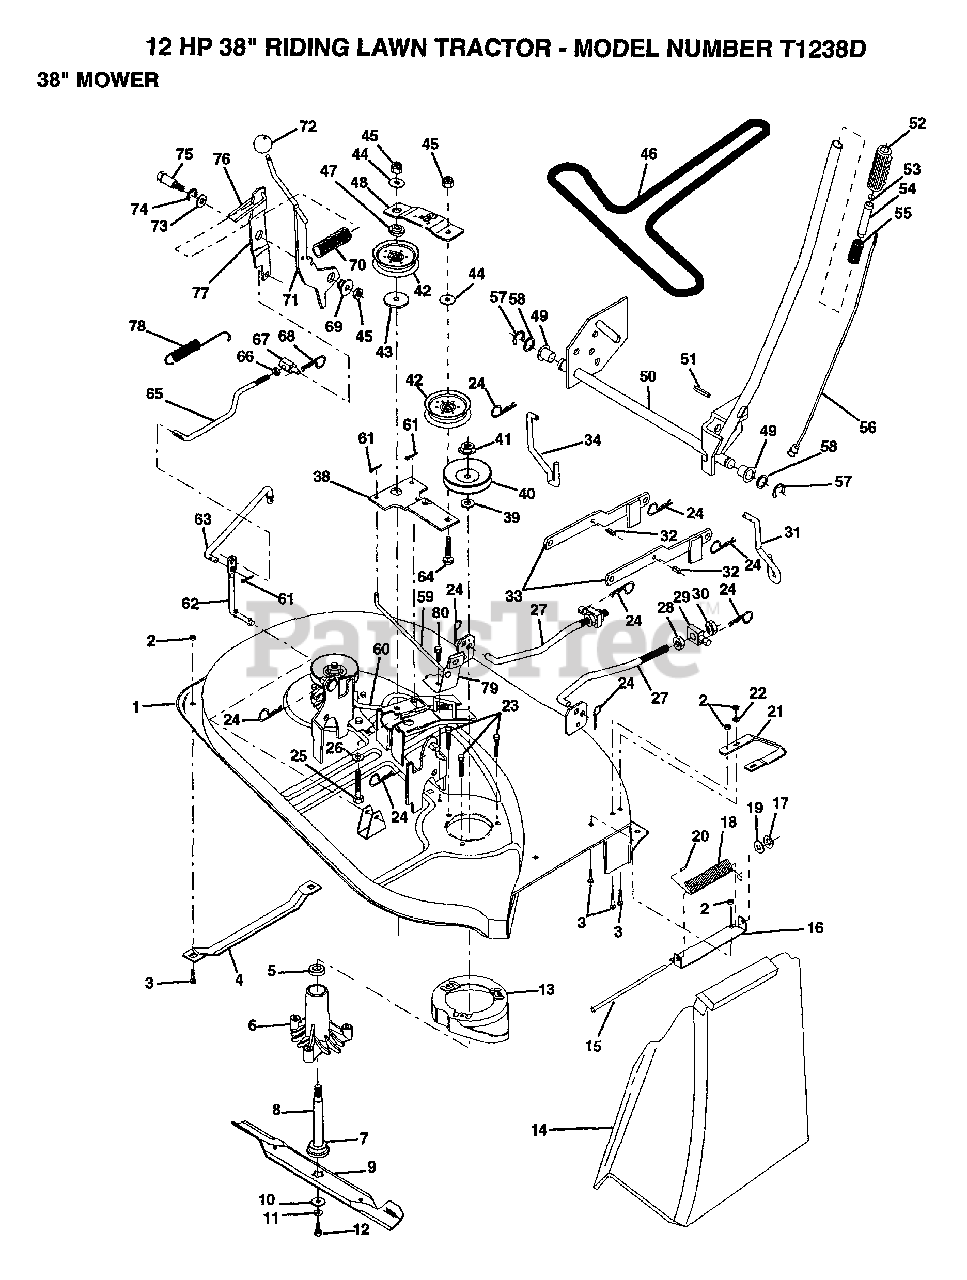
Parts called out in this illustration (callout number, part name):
3	BOLT
4	RUNNER-LH M
5	BEARING
6	HSG ASM MANDREL
7	BEARING.BALL
10	WASHER BLADE
12	BLADE BOLT
14	DEFLECTOR-SHLD T
15	ROD-HINGE T
17	NUT PUSH M
19	WASHER
20	CAP-SLEEVE LT
21	RUNNER RH
22	WASHER M
25	BOLT
26	WASHER GT
27	LINK.FRONT
28	NUT
29	TRUNION
30	NUT.LK.W/WSH.1/2.
31	LINK LIFT RH
32	SPRING PIN
33	SUSP ARM REAR
34	LIFT LINK LH
35	NUT
38	IDLER ARM ASSY
39	WASHER
42	FLAT IDLER PULLEY
43	SPACER RETAINER
44	WASHER GT
46	BELT-V.88.12.MW
47	RETAINER SPACER
48	IDLER ARM STIFF
49	NYLON BEARING
51	PIN-GROOVE LT
52	GRIP
58	WASHER
59	BRAKE ROD RH
60	BRAKE ROD LH
62	PIVOT ROD
63	CLUTCH ROD SECOND
64	BOLT
66	NUT
67	TRUNION
68	RETAINER M
69	BUSHING
71	CLUTCH ARM PRI AS
73	WASHER
74	RING
75	SHOULDER BOLT
76	SPRING KEEPER
77	CLUTCH ARM SECOND
78	RETURN SPRING
79	BRAKE ASM
80	SCREW
